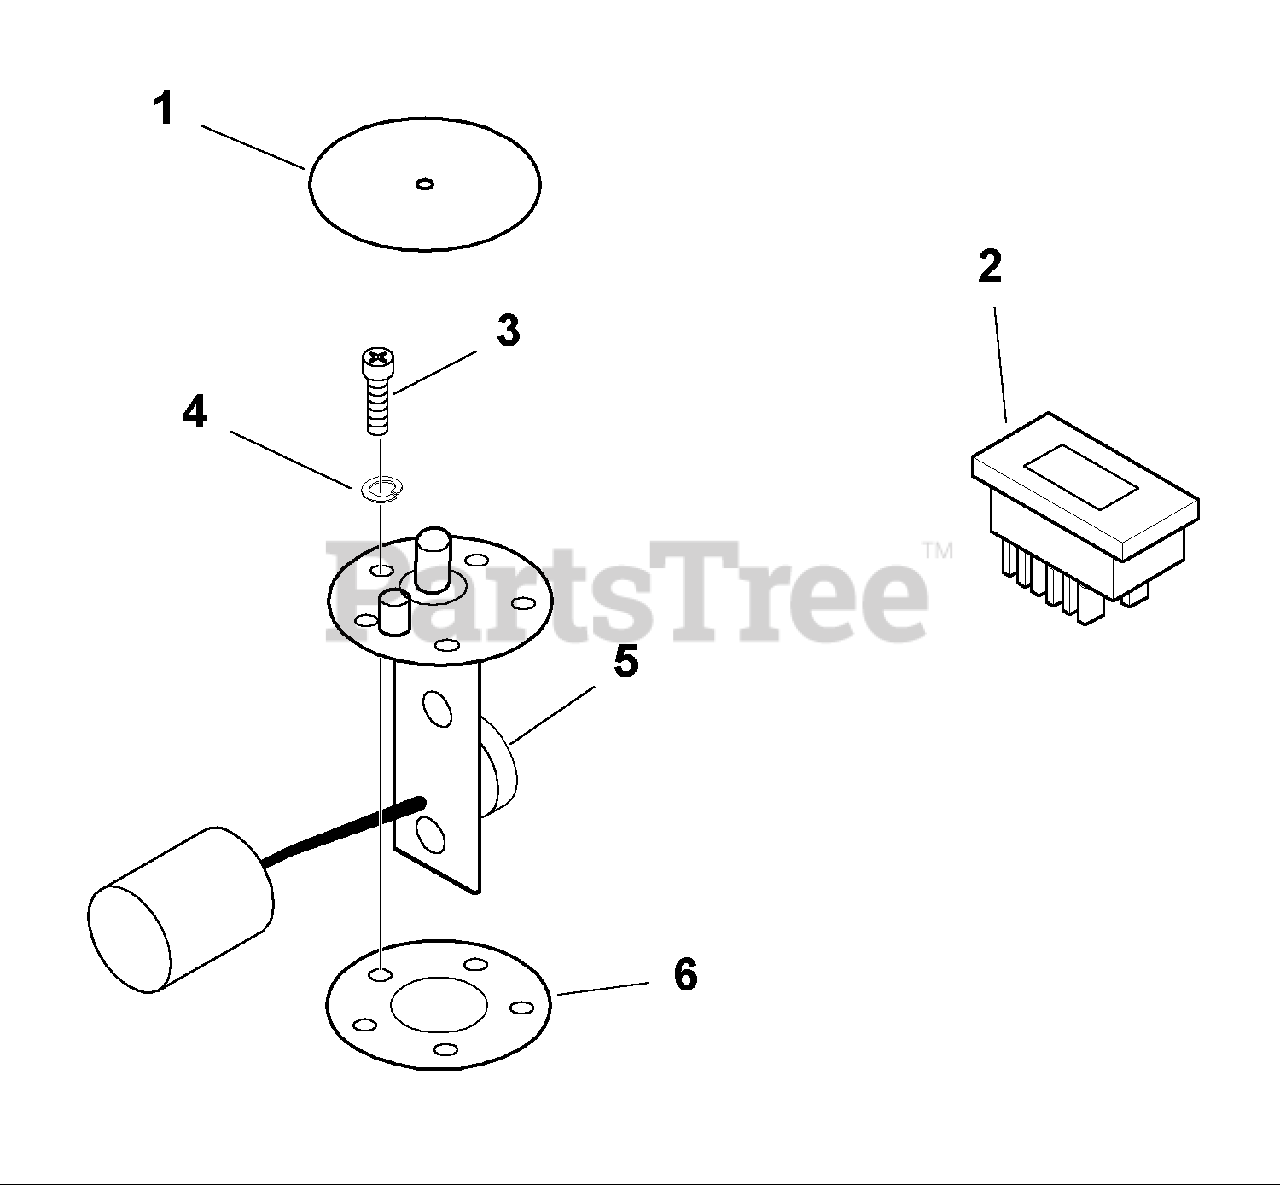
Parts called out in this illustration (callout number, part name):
2	INSTRUMENT PANEL
3	SCREW, #10-32 x 1/2
4	LOCKWASHER, #10
5	SENDER, Fuel
6	GASKET, Sender
